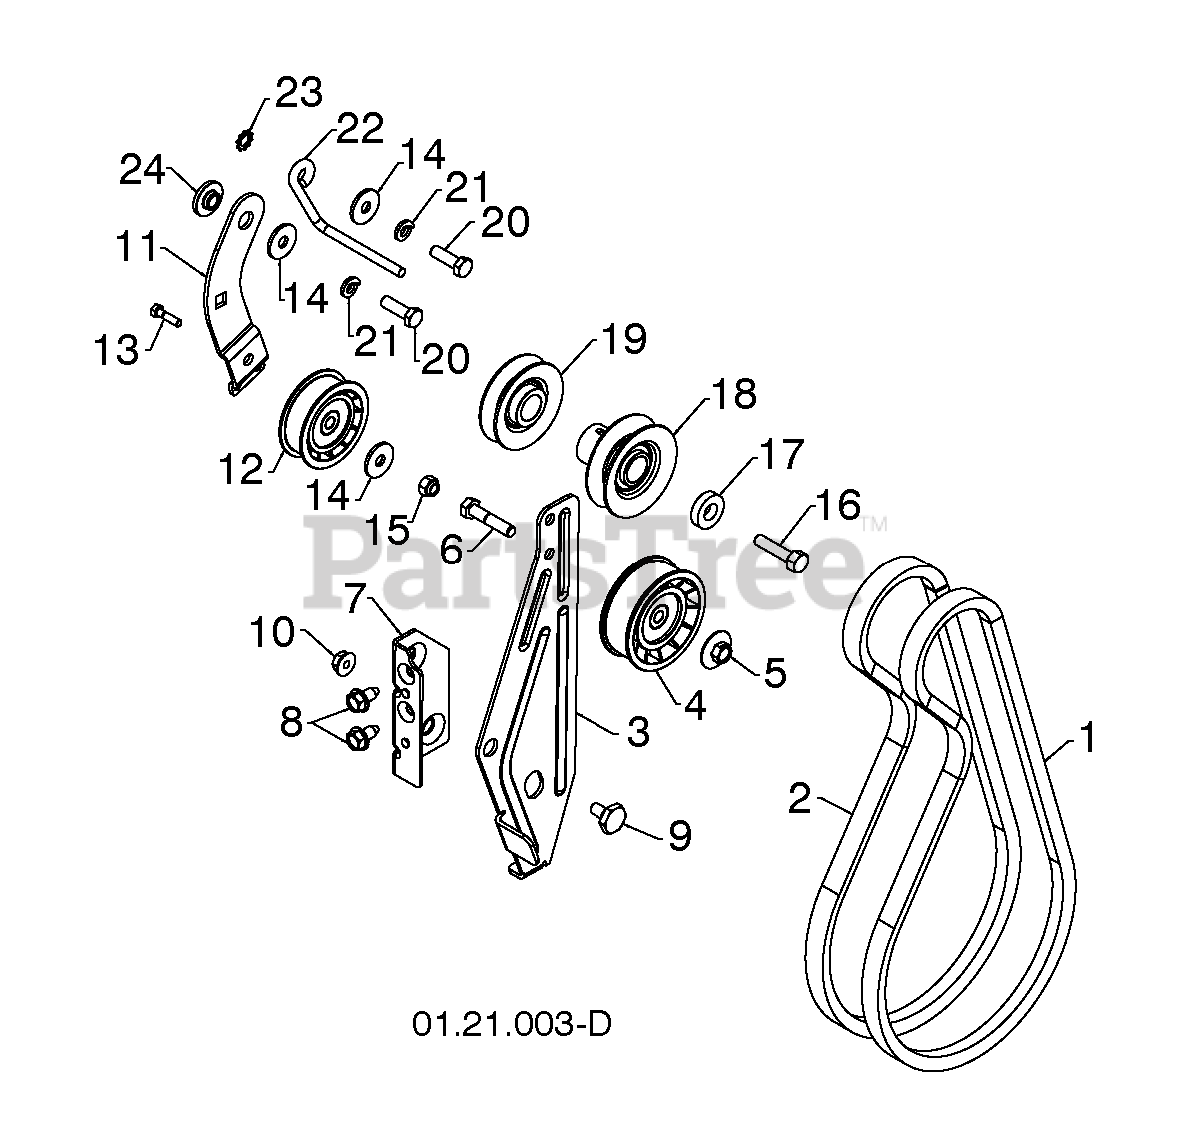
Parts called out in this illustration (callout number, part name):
1	BELT.V.IMPELLER
2	V-BELT TRACTION 34.25
3	ARM.IDLER.BRAKE.
4	PULLEY.W/SPACER.2.75
5	RP BRACKET.IDLER.PIVOT
6	NUT.FLANGE.HEX.5/16X18.BLACK
7	HEX BOLT
8	BOLT.SHOULDER.1/2X12
9	BOLT.5/16HEX.WHS.HD
10	NUT.LOCK.5/16-18
11	ARM, IDLER
12	PULLEY.W/SPACER.2.25
13	STEEL WASHER
14	NUT.71038.31-18.HEX.NYLOCK
15	BOLT.5/16-18X1-1/4 FULL.THREAD
16	SCREW, HEX HD 3/8-24 X 1-3/8
17	WASHER, FLAT 3/8
18	PULLEY.IMPELER.
19	PULLEY.ENG.TRACTION
21	WASHER.LOCK.HVY.HLCL.SPR.5/16
22	BELT.GUIDE.RH
23	WASHER EXT TOOTH LOCK 5/16
24	RP BUSHING, IDLER PIVOT
